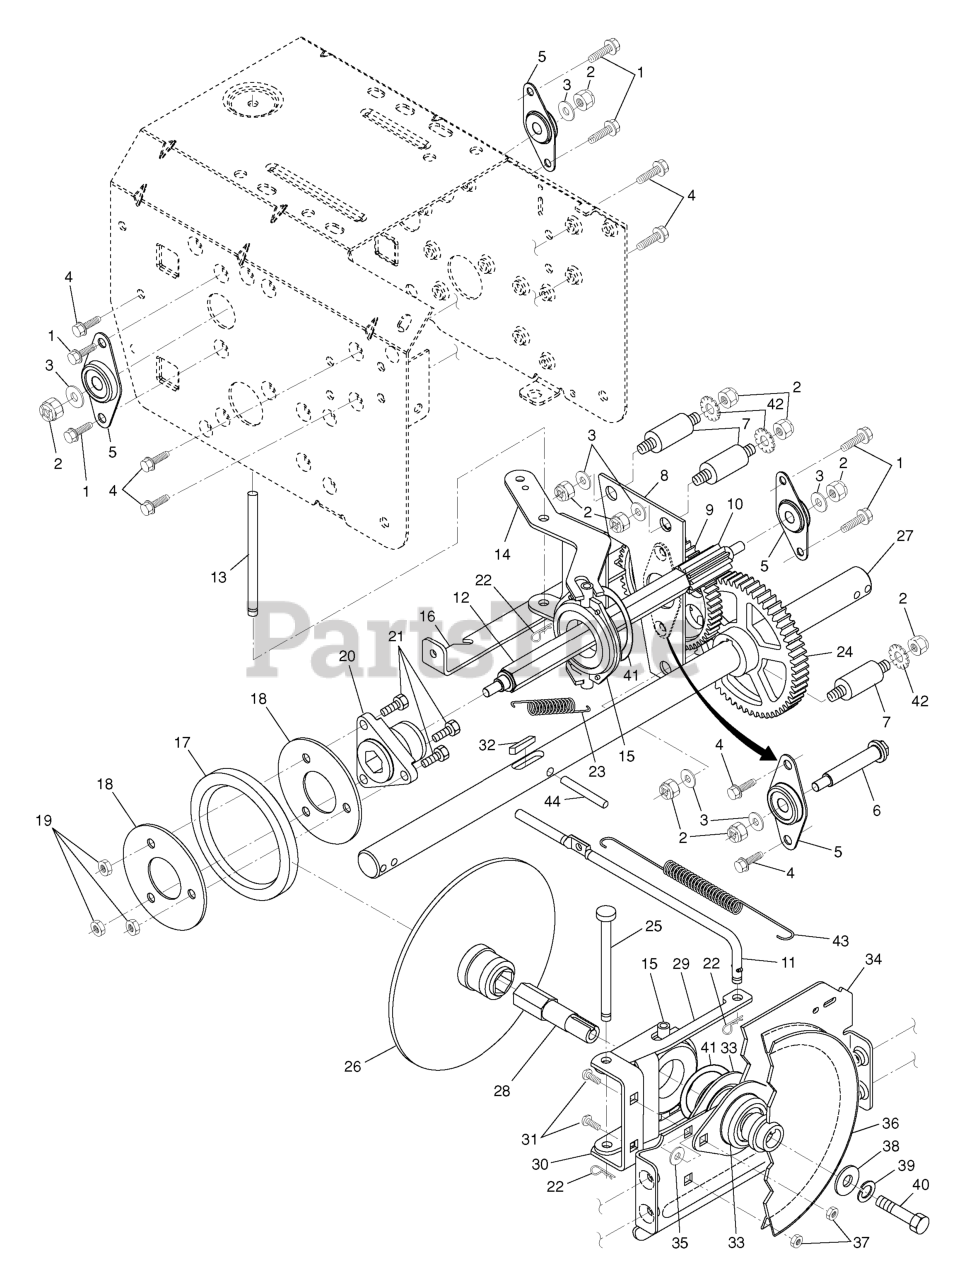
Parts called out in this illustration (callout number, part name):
2	NUT.71038.31-18.HEX.NYLOCK
3	WASHER.20X8.5
4	Screw, Hex Head 5/16-18 x 1/2
5	BEARING, FLANGE
6	SHAFT, AUXILIARY
7	SPACER, PLATE
8	AUXILLARY PLATE
9	GEAR, INTERMEDIATE
10	GEAR, PINION
11	ROD.CLUTCH.YELLOW.ZINC
12	SHAFT.HEX.LONG
13	PIN, PIVOT
14	LEVER, SPEED CONTROL
15	TRUNNION BEARING ASSY
16	BRACKET, PIVOT, SHIFT
17	RING, RUBBER WHEEL
18	PLATE.RUBBER.WHEEL
19	NUT.CENTERLOCK.5/16-
20	HUB, RUBBER WHEEL
21	BOLT
22	RETAINER CLIP PM
23	SPRING, BIAS
24	GEAR, AXLE (58T)
25	PIN, PIVOT LEVER
26	DRIVE PLATE WELDMENT
27	SHAFT.AXLE.16".POWER.STEER.SNO
28	SHAFT.HEX.SHORT
29	LEVER.SHIFTER.PLATE.BLACK
30	BRACKET, SHIFTER SUPPORT
31	BOLT
32	KEY, SQUARE 1/4 X .875
33	BEARING FLANGE
34	PLATE.DRIVE.MOUNTING.BLACK
35	SPACER, BEARING
36	PULLEY.TRACTION.7.75
37	NUT.FLANGE.5/16
38	WASHER, FLAT
39	WASHER.LOCK.HVY.HLCL.SPR.5/16
40	Screw, Hex Head 5/16-18 x 3/4
41	RETAINING RING (2 2)(3 2)
42	WASHER EXT TOOTH LOCK 5/16
43	SPRING.RETURN
44	PIN.ROLL.3/16
